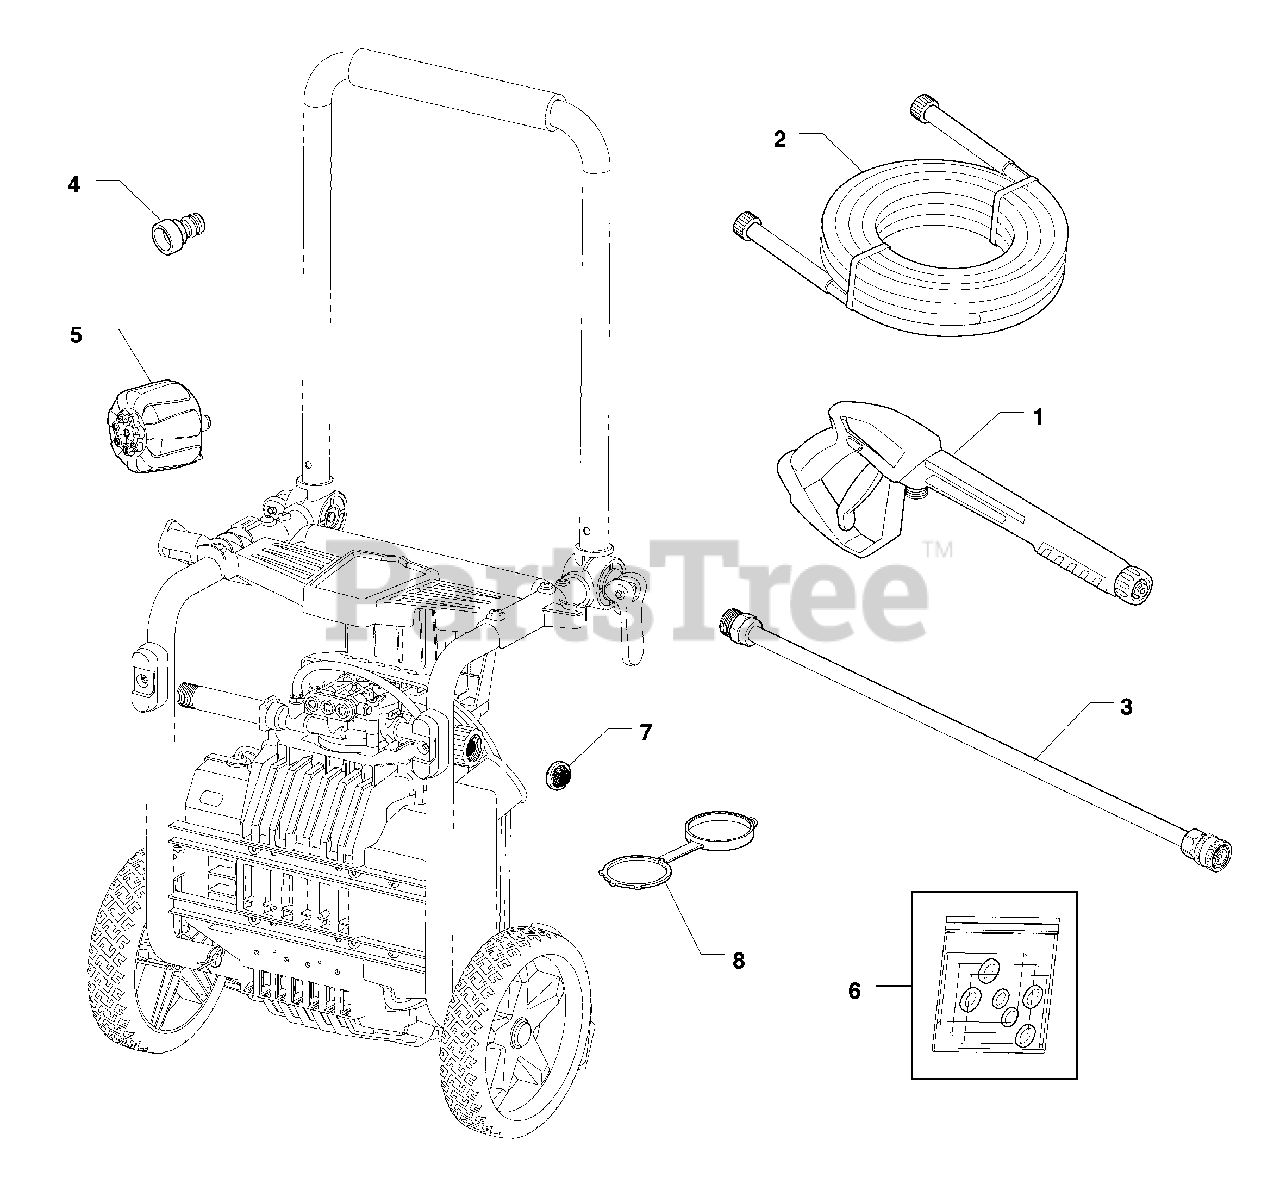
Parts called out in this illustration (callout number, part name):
3	EXTENSION, QC
6	KIT-O-RING MAINTENANCE
7	FILTER-GARDEN HOSE
